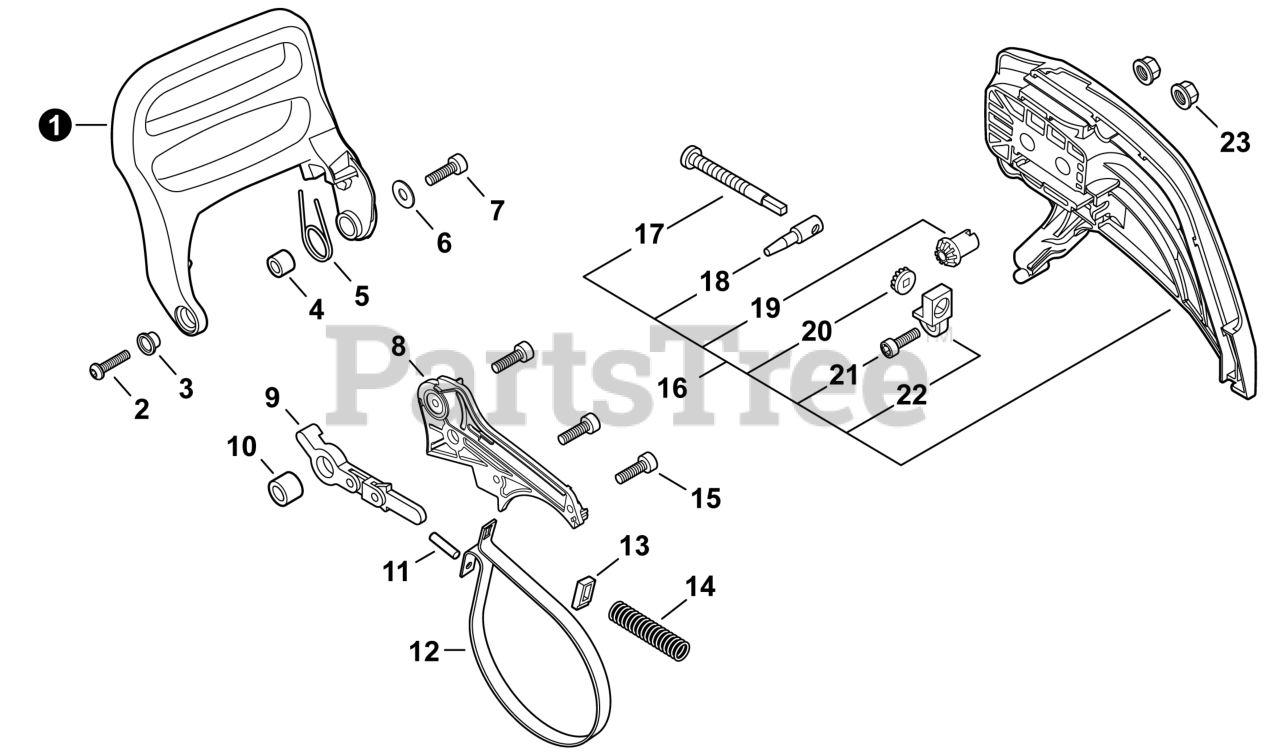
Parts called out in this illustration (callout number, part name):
1	LEVER, BRAKE
2	BOLT, TORX 5x20
3	COLLAR 10
4	SPACER 8x12x9
5	SPRING, TORSION
6	WASHER 4.2x16.5x1
7	BOLT, TORX 4x20
8	COVER, BRAKE
9	CONNECTOR, BRAKE
10	SPACER 8x12x9
11	PIN, SPRING 3x9.8
12	BAND, BRAKE
14	SPRING, COMPRESSION
15	BOLT, TORX 4x12
16	COVER ASSY, CLUTCH
17	SCREW, CHAIN TENSION
18	TENSIONER, CHAIN
19	GEAR, BEVEL
20	GEAR, BEVEL
21	BOLT, TORX 4x12
22	COLLAR 8
23	NUT, FLANGE M8x1.25
